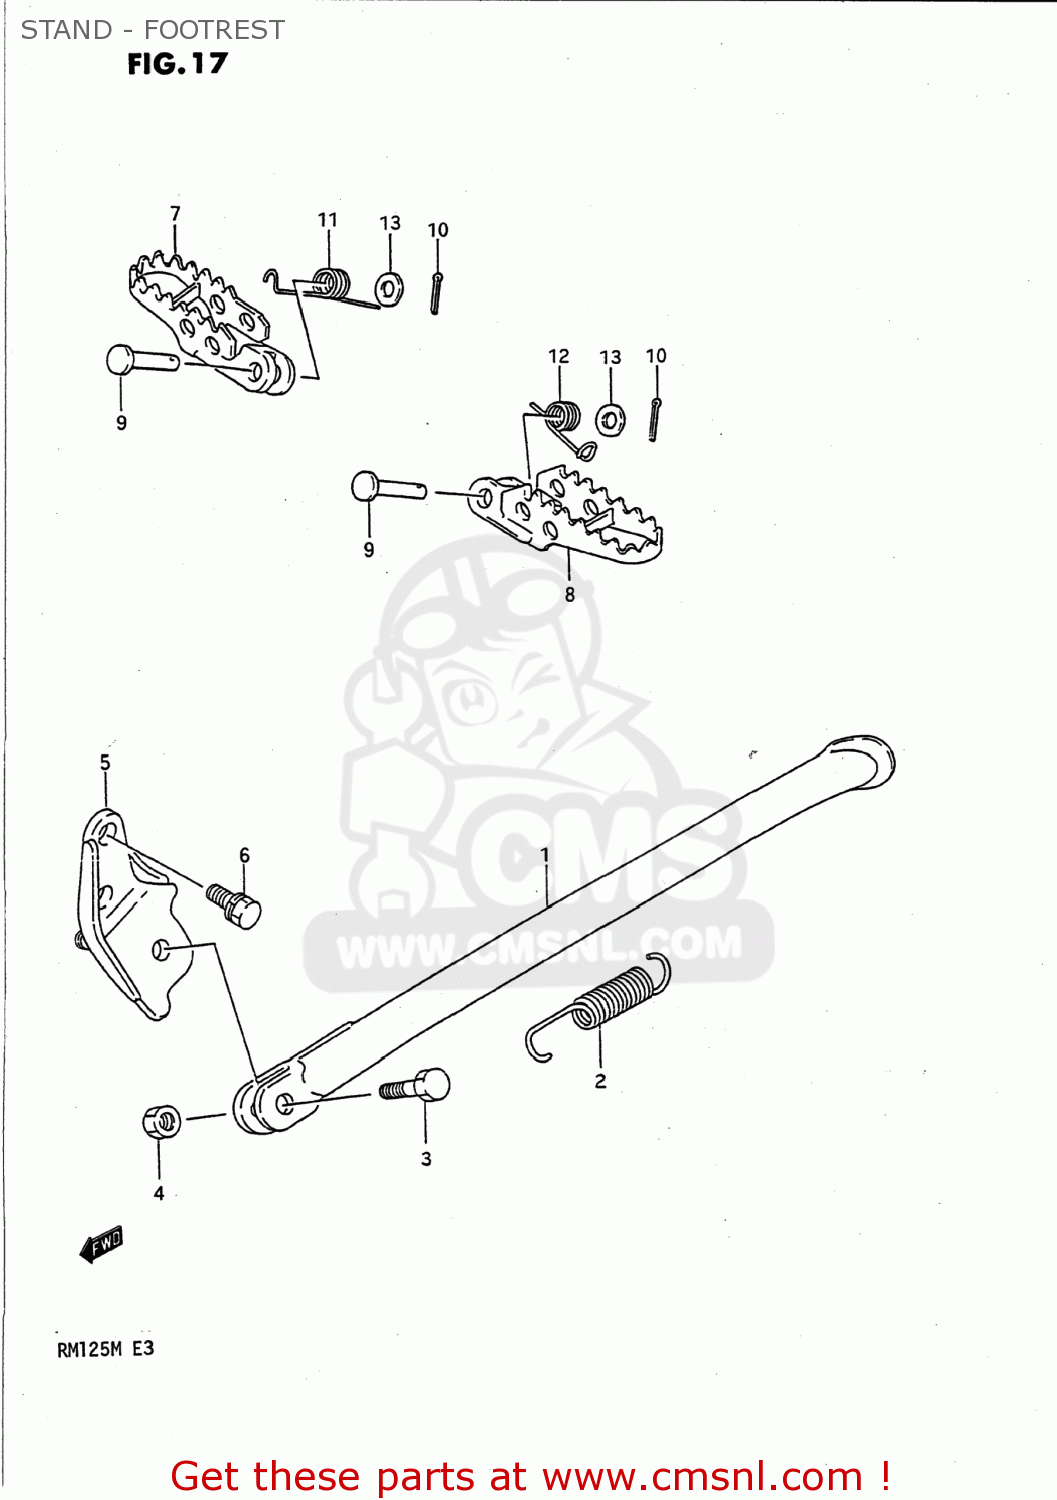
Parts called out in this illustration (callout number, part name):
1	STAND,SIDE
2	SPRING
3	BOLT(10X30)
4	NUT
5	BRACKET,SIDE STAND
6	BOLT
7	FOOTREST,FRONT,RIGHT
8	FOOTREST
9	PIN
10	PIN 25X20
11	SPRING
12	SPRING
13	WASHER
